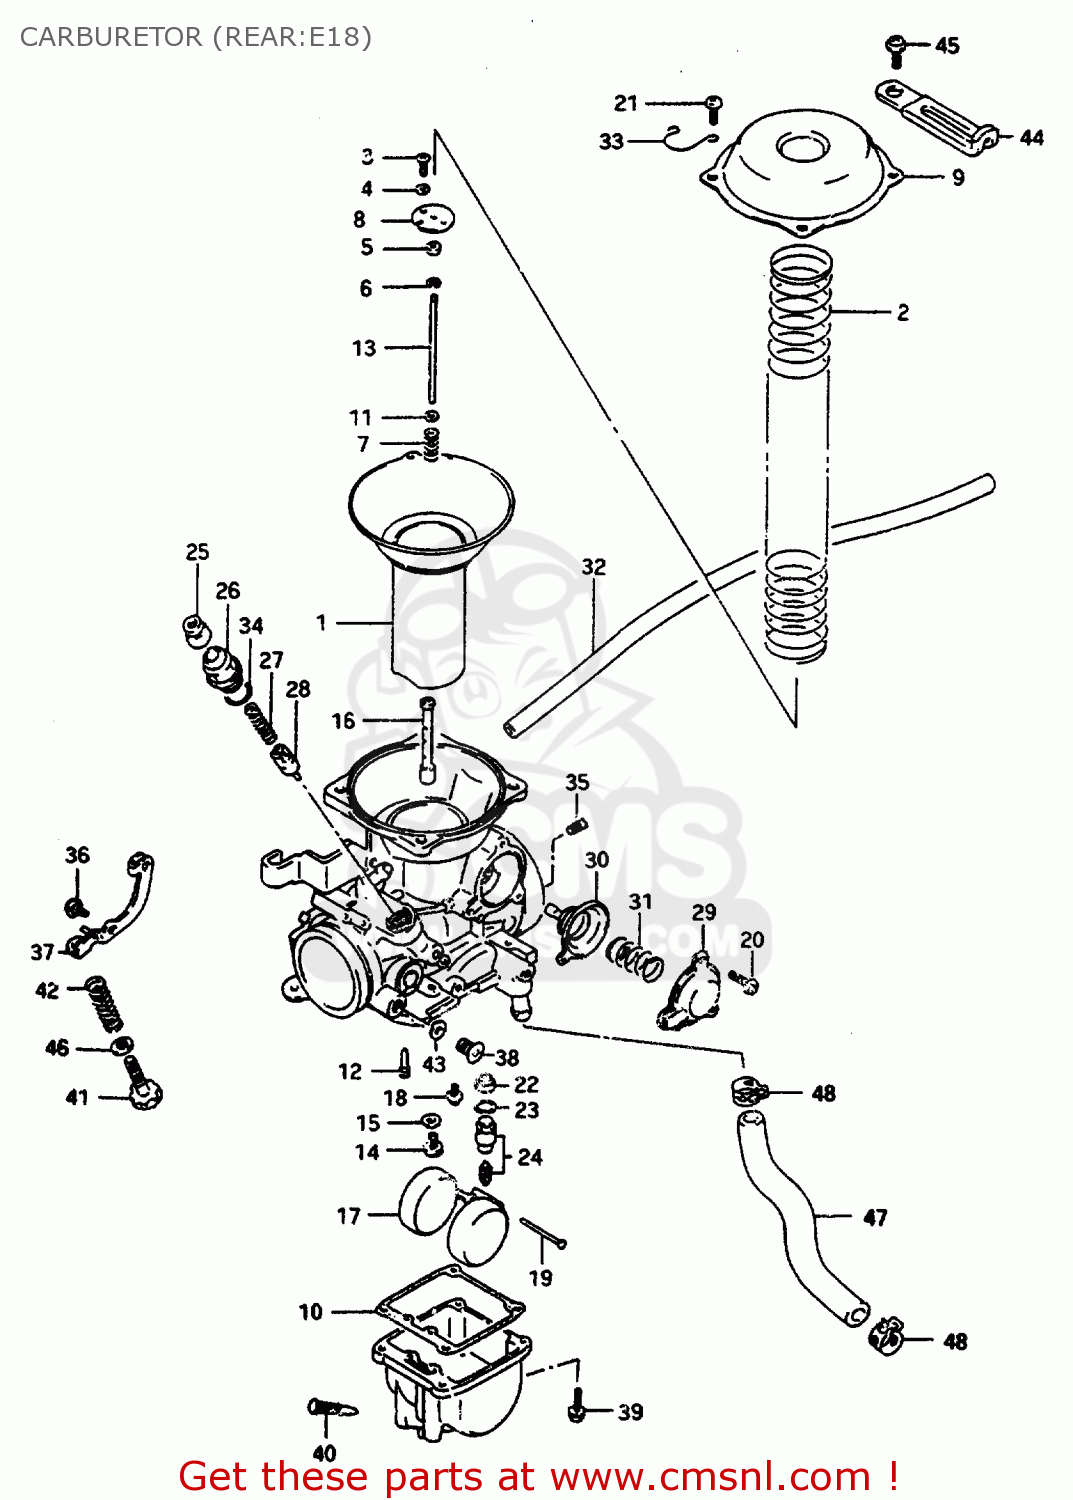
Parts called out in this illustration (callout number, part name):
1	DIAPHRAGM ASSY
2	SPRING,DIAPHRAGM
3	SCREW
4	WASHER,LOCK
5	RING
6	CLIP
7	SPRING
8	PLATE
9	COVER,DIAPHRAGM
10	GASKET,FLOAT CHAMBER (NAS)
11	WASHER
12	JET,PILOT(30)
13	NEEDLE,JET
14	JET,MAIN(105)
15	WASHER,NEEDLE NOZZLE
16	JET,NEEDLE
17	FLOAT
18	SCREW
19	PIN,FLOAT
20	SCREW
21	SCREW
22	FILTER
23	O-RING,NEEDLE VALVE
24	VALVE ASSY,NEEDLE
25	CAP
26	HOLDER,GUIDE
27	SPRING
28	PLUNGER,STARTER
29	COVER
30	DIAPHRAGM ASSY
31	SPRING
32	HOSE(5X8.2X600)
33	CLIP
34	O RING
35	JET,AIR(60)
36	SCREW
37	LEVER,ASSY
38	SCREW
39	SCREW
40	SCREW,DRAIN
41	ADJUSTER
42	SPRING
43	SCREW
44	CLAMP(L:65)
45	SCREW
46	WASHER
47	GASKET,DRAIN PLUG (NAS)
48	CLIP
49	SCREW
50	WASHER
51	HOSE,FUEL PUMP & CARBURETOR
52	CLIP
